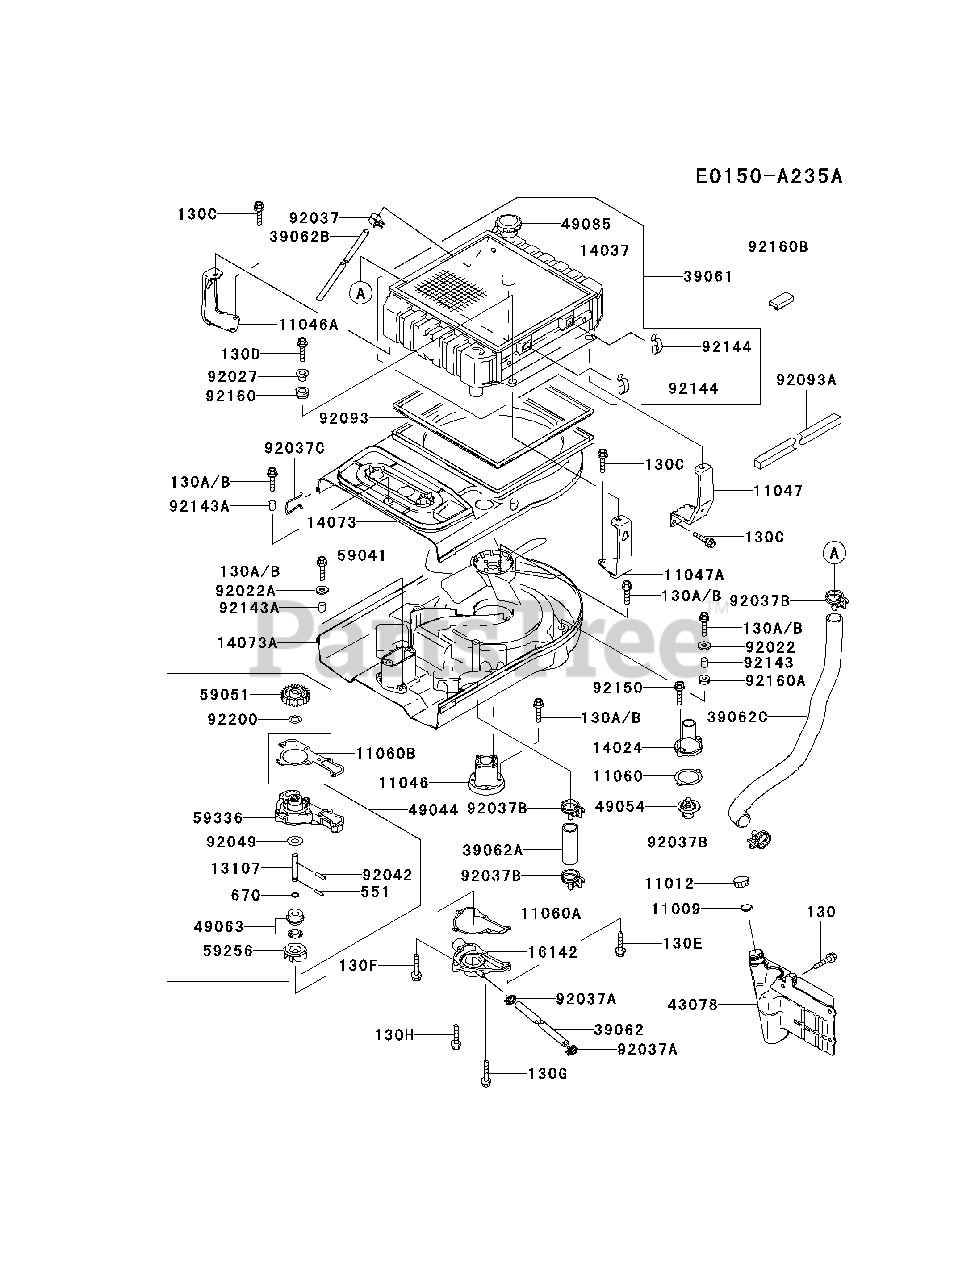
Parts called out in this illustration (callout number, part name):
130	BOLT-FLANGED
130A	BOLT-FLANGED
130B	BOLT-FLANGED
130C	BOLT-FLANGED
130D	BOLT-FLANGED
130E	BOLT-FLANGED
130F	BOLT-FLANGED
130G	BOLT-FLANGED
130H	BOLT-FLANGED
551	PIN-DOWEL
670	O RING
92150	BOLT,6X20
